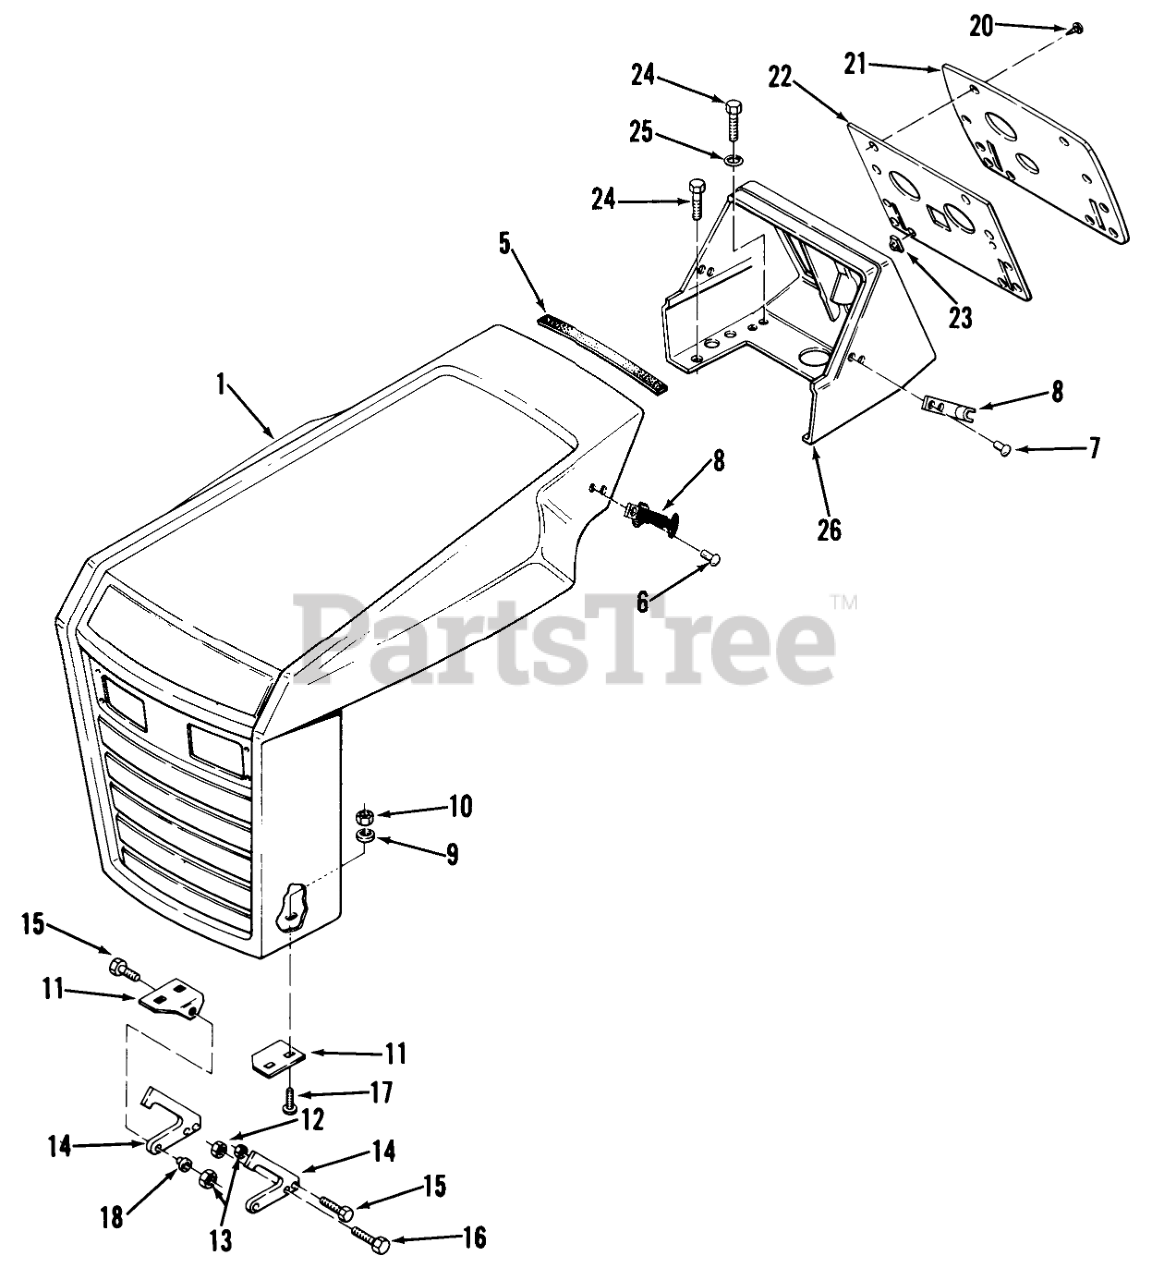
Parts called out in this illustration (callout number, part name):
5	TRIM-CONSOLE
6	RIVET -4
7	RIVET
8	ASSY-FLEX DRAW LATCH
10	Nut
11	BRKT-HOOD PIVOT LH
11	BRKT-HOOD PIVOT RH
12	Nut
13	Nut
14	BRACKET-HOOD SUPT
15	Bolt
16	Bolt
17	Bolt-Carriage
18	BUSHING-PIVOT
20	SCREW BLACK
21	PLATE-INSTRUMENT
22	Back-Up Plate
23	SPEED NUT
24	SCREW
25	WASHER 5/16 SAE
26	CONSOLE
